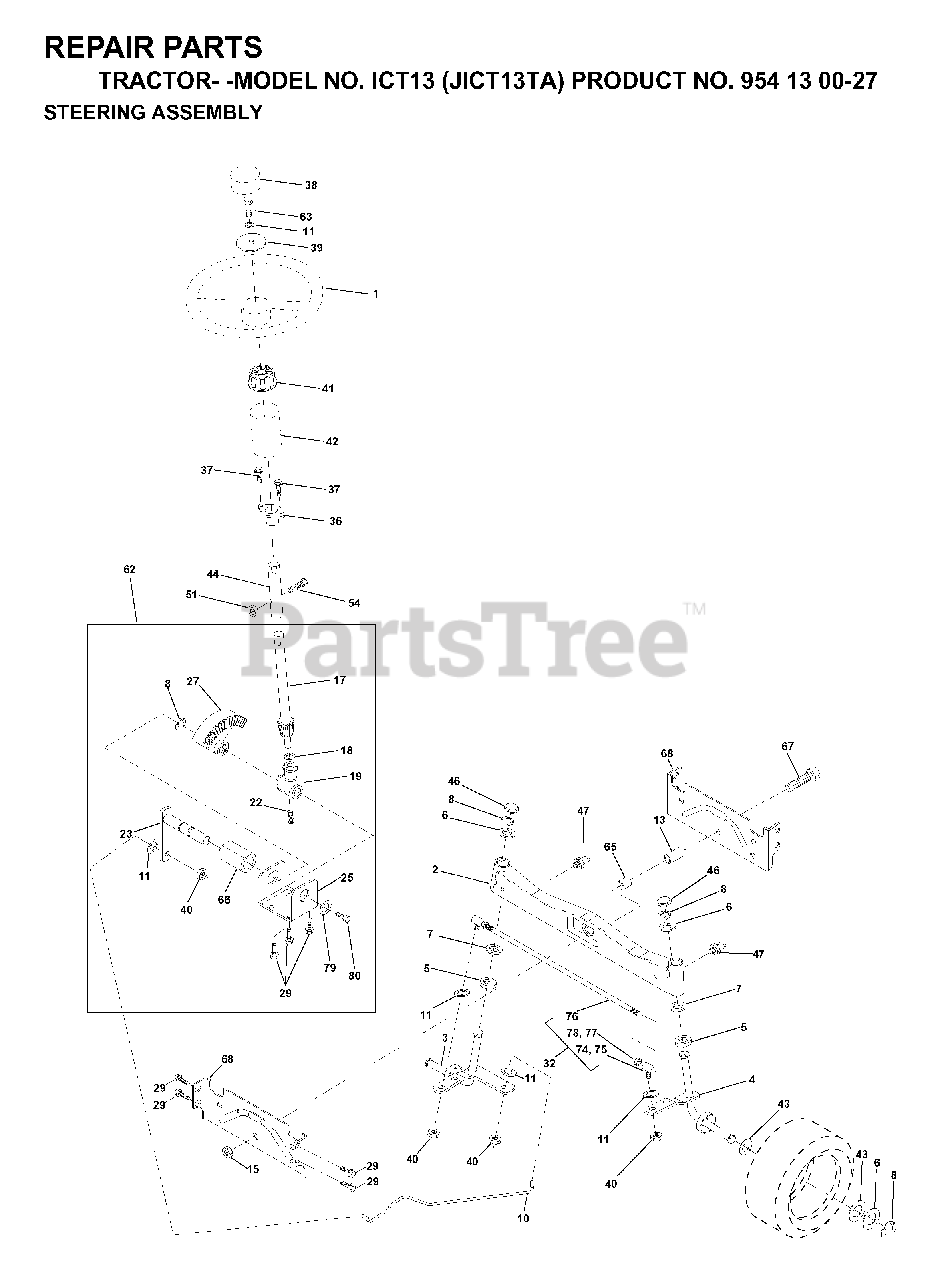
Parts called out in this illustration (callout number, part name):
2	FRONT AXLE ASSY
3	SPINDLE ASM LH
4	SPINDLE ASM RH
8	RING CLIP
10	LINK.DRAG.DROPPED.LT
11	WASHER, LOCK 3/8
13	SPACER, FRT AXLE BRNG
15	NUT-LOC,FLANGE LT
17	SHAFT ASM STEERING
18	THRUST WASHER
19	STEERING SHAFT SUPPORT
22	SCREW.HX.WSH.HD
23	SHAFT ASSY PITTMAN
25	BRACKET STEERING
27	GEAR.SECTOR
29	SCREW
32	ROD ASSY/TIE BALL
36	BUSHING, STEERING
38	RP INSERT
39	WASHER T
40	GRIPCO NUT
41	ADAPTER LT
42	STEERING BOOT, GRAY
44	EXT SHAFT STEERING
46	CAP.SPINDLE
47	ZERK M
51	NUT.71038.31-18.HEX.NYLOCK
54	BOLT.5/16-18X1-1/4 FULL.THREAD
62	STEERING KIT
65	SPACER AXLE
66	BEARING ARM
67	BOLT.HEX.FINISHED.5/8
68	AXLE, BRACE
74	JOINT
76	TIE ROD
80	BOLT.HX.NYLON3/8-16X
